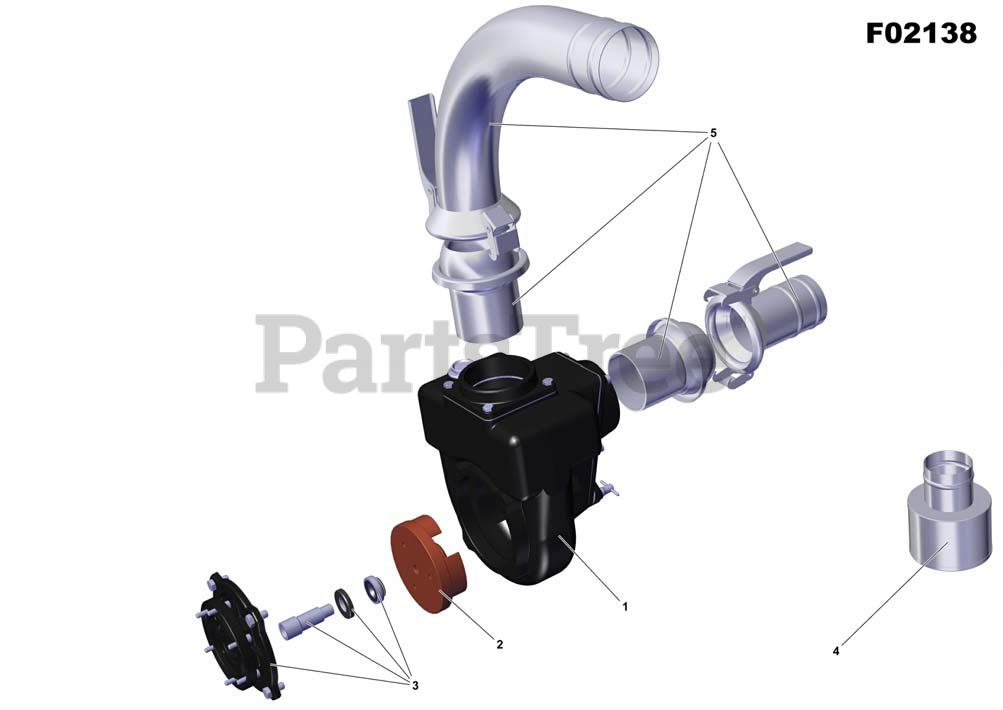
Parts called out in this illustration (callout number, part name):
1	Pump Casing Assy. See Group: Pump Casing Assy.
3	Screws Set See Group Screws Set
5	ELBOW ASSEMBLY
